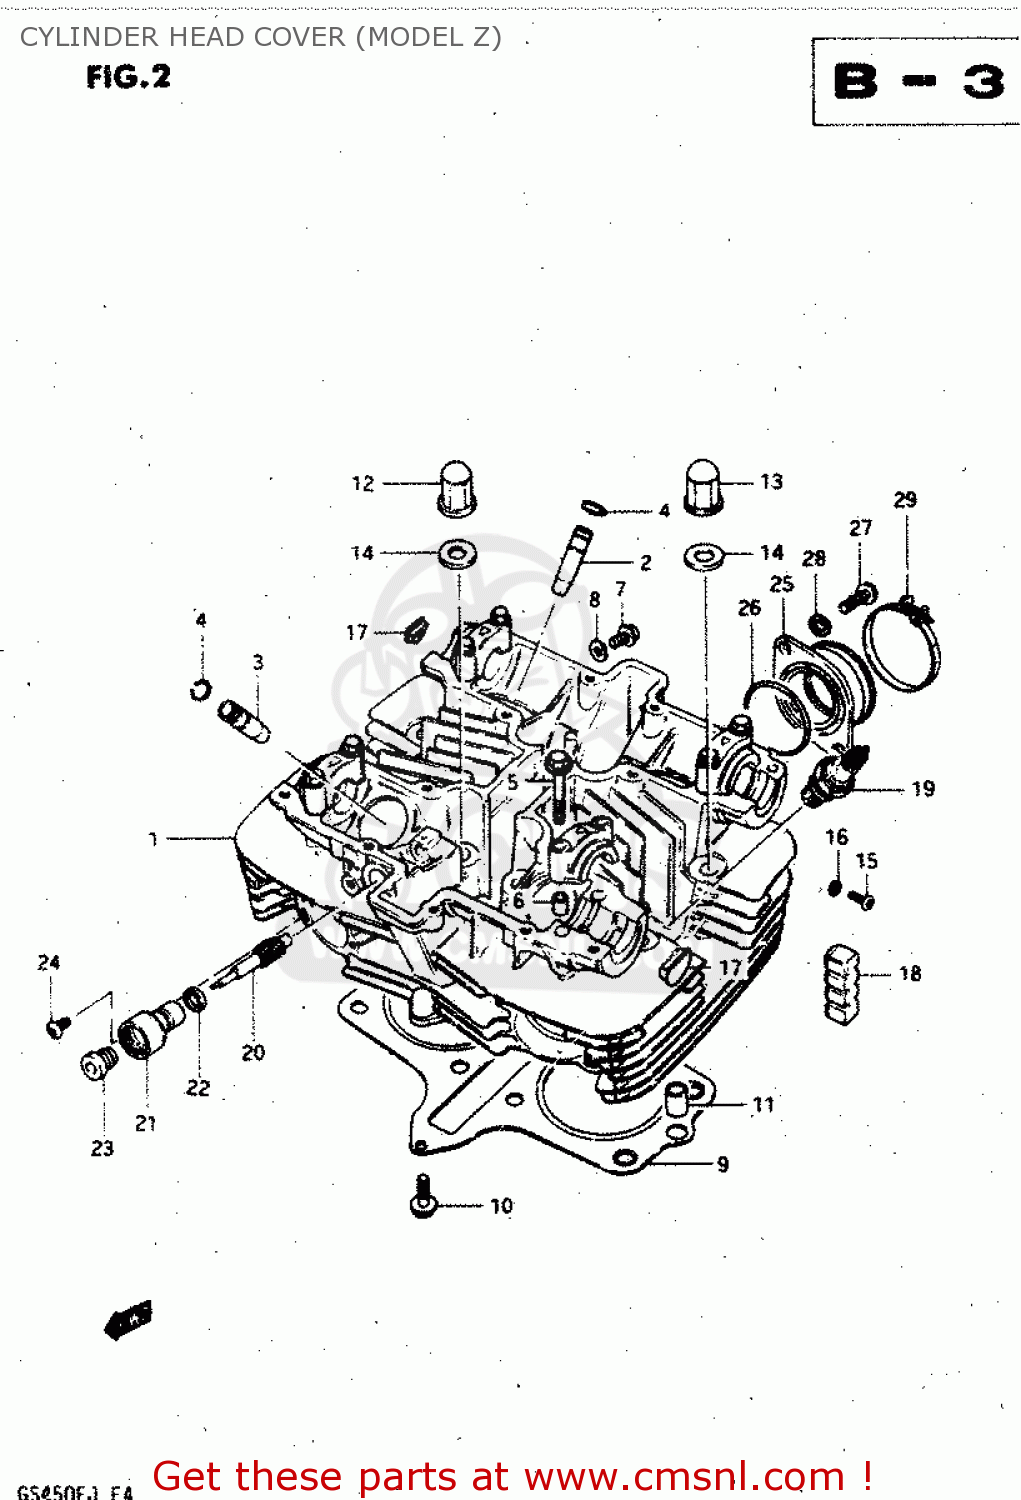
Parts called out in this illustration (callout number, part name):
1	COVER,CYLINDER HEAD
2	GASKET,CYLINDER HEAD COVER (MCA)
3	BOLT,UNDER
4	BOLT
5	BOLT
6	CAP,CYLINDER HEAD COVER
7	SCREW
8	COVER,BREATHER
9	GASKET (MCA)
10	BOLT,REAR
11	COVER,BREATHER
12	SEPARATOR,OIL BREATHER
